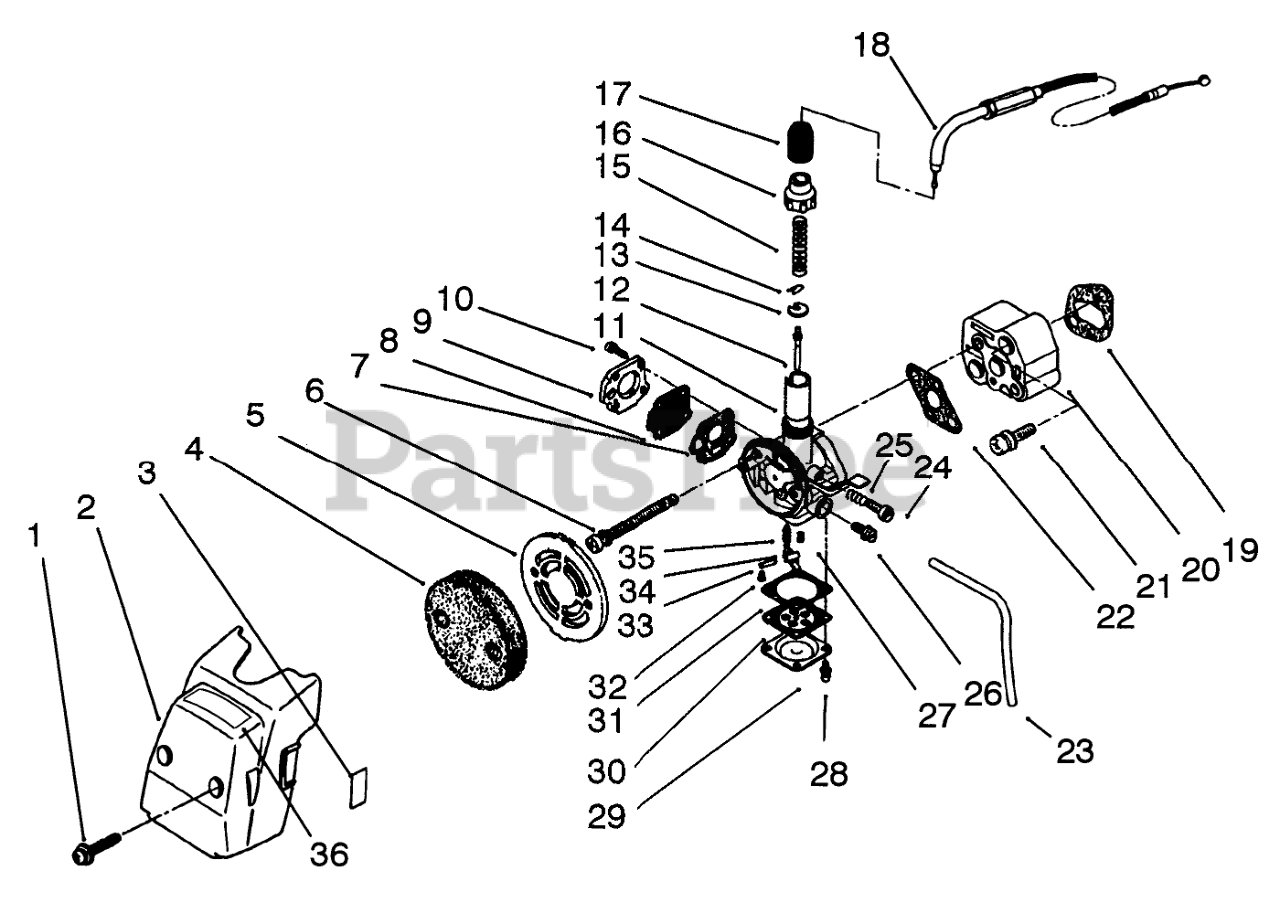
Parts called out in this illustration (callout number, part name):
1	SCREW & WASHER
2	CLEANER CASE
3	CHOKE LABEL
4	ELEMENT
6	SCREW W/ WASHER
7	PUMP COVER GASKET
8	PUMP DIAPHRAGM
9	Pump Cover Assembly
10	SCREW W/ WASHER
11	THROTTLE VALVE
12	NEEDLE JET
13	SPRING RETAINER
14	NEEDLE CUP
15	SPRING
17	AIR SEAL
18	WIRE, THROTTLE
19	INSULATOR GASKET
20	INSULATOR
21	SCREW & WASHER
22	CARB GASKET
23	FUEL TUBE
24	Screw-Adjusting
25	ADJ. SCREW SPRING
26	MAIN NEEDLE
27	VALVE SPRING
28	SCREW W/ WASHER
29	DIAPHRAGM COVER
30	MAIN DIAPHRAGM
31	DIAPHRAGM GASKET
32	FLOAT SCREW
33	FLOAT PIN
34	FLOAT ARM
35	FLOAT VALVE
36	Decal-Fuel Mix
